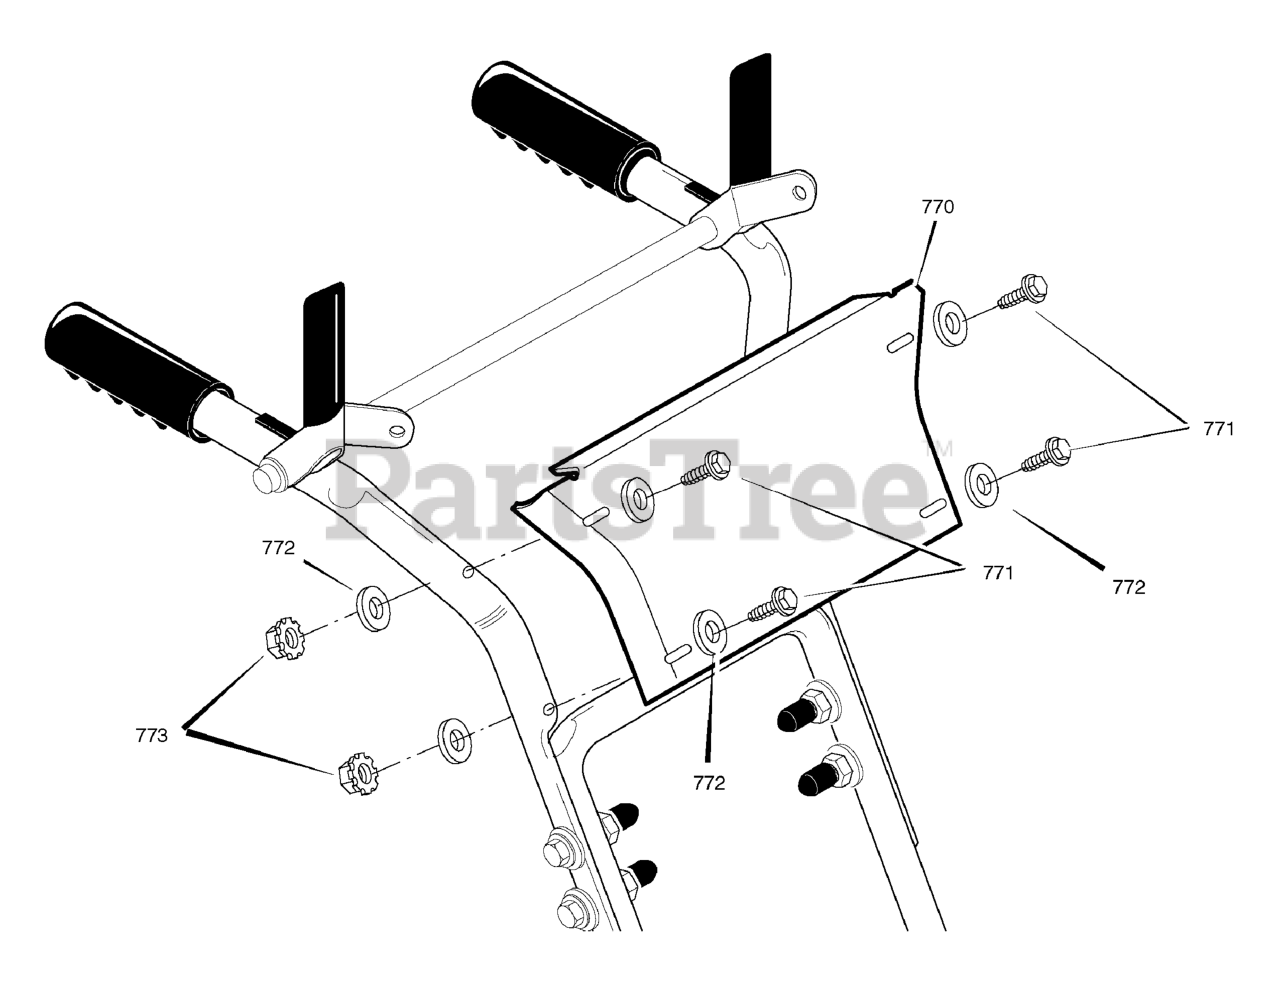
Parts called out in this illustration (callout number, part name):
770	PANEL
771	BOLT, Carriage
772	WASHER
773	NUT
